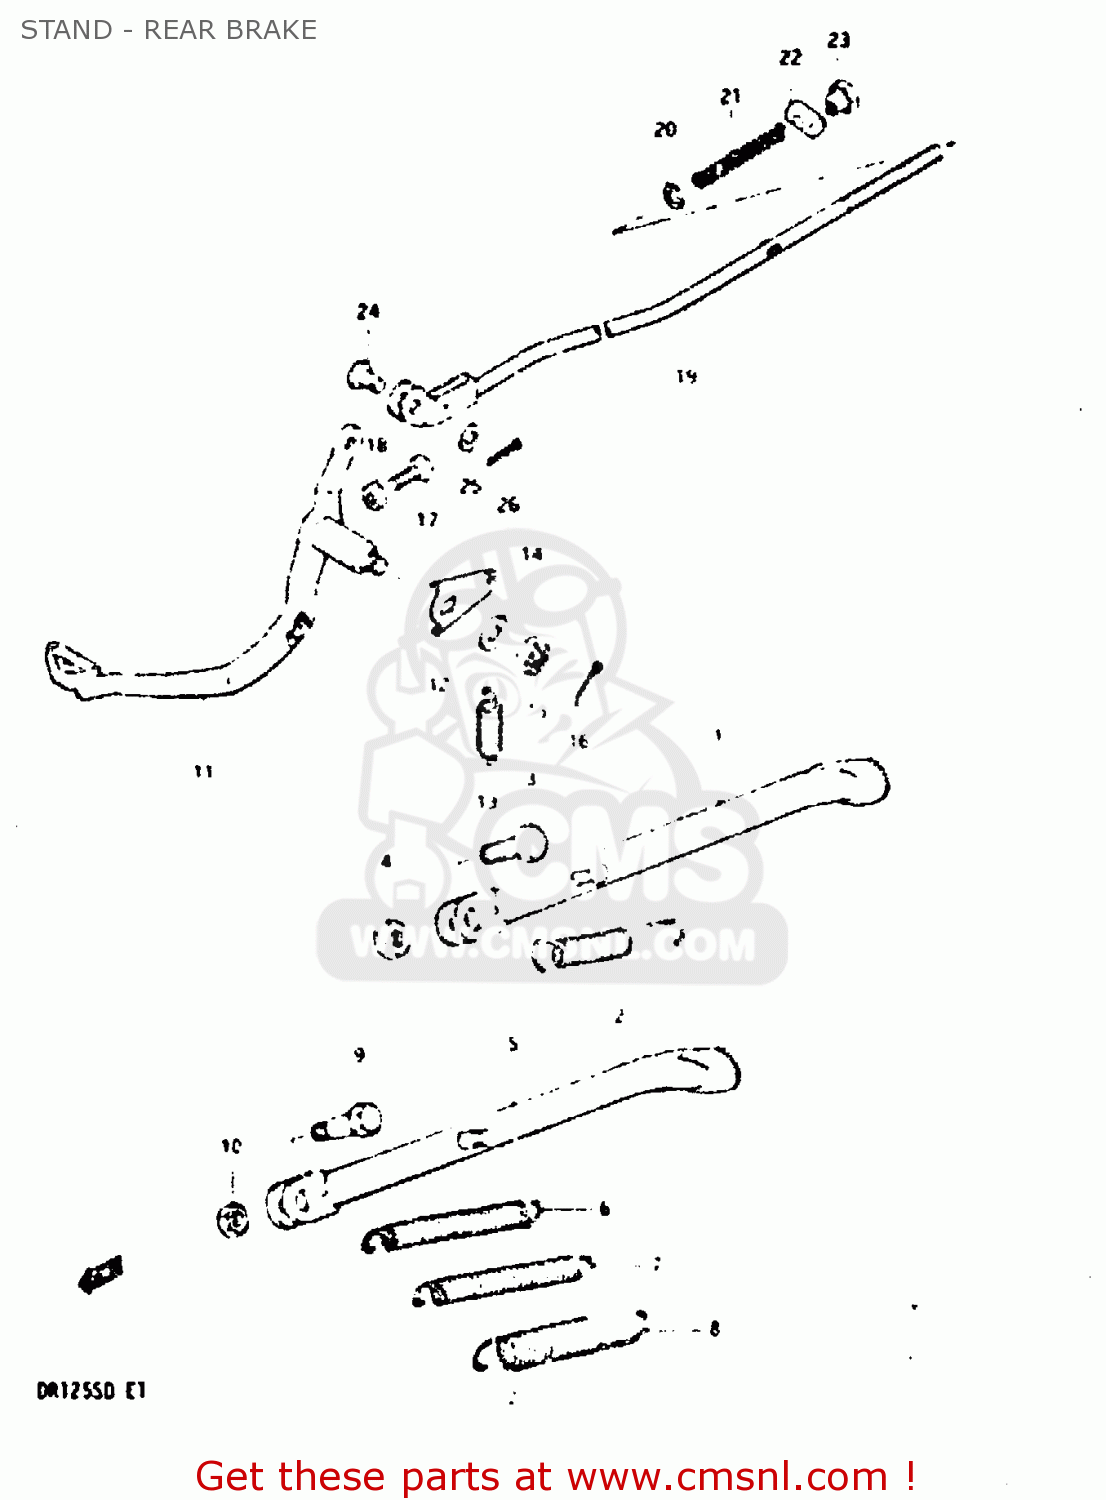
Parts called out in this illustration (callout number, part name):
1	STAND PROP
2	SPRING
3	BOLT(10X30)
4	NUT
11	PEDAL,BRAKE
12	ARM,BRAKE RETURN SPRING
13	SPRING
14	WASHER
15	NUT 8MM
16	PIN 20X20
17	BOLT(6X23)
18	NUT
19	ROD ASSY REAR BRAKE
20	WASHER
21	SPRING
22	PIN
23	NUT
24	PIN
25	WASHER
26	PIN 20X20
